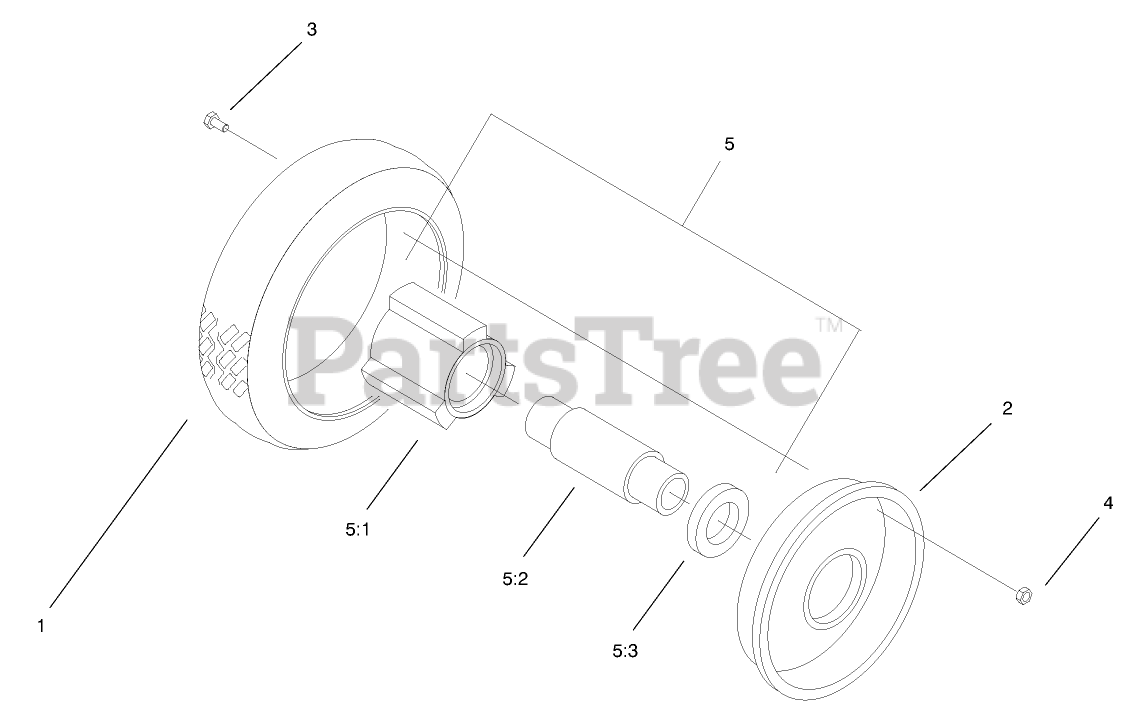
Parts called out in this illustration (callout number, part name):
3	SCREW-HH
4	NUT-LOCK, NI
5	Hub Brg ASM
5:1	HUB-BEARING
5:2	SPACER-BEARING
5:3	BEARING-WHEEL
